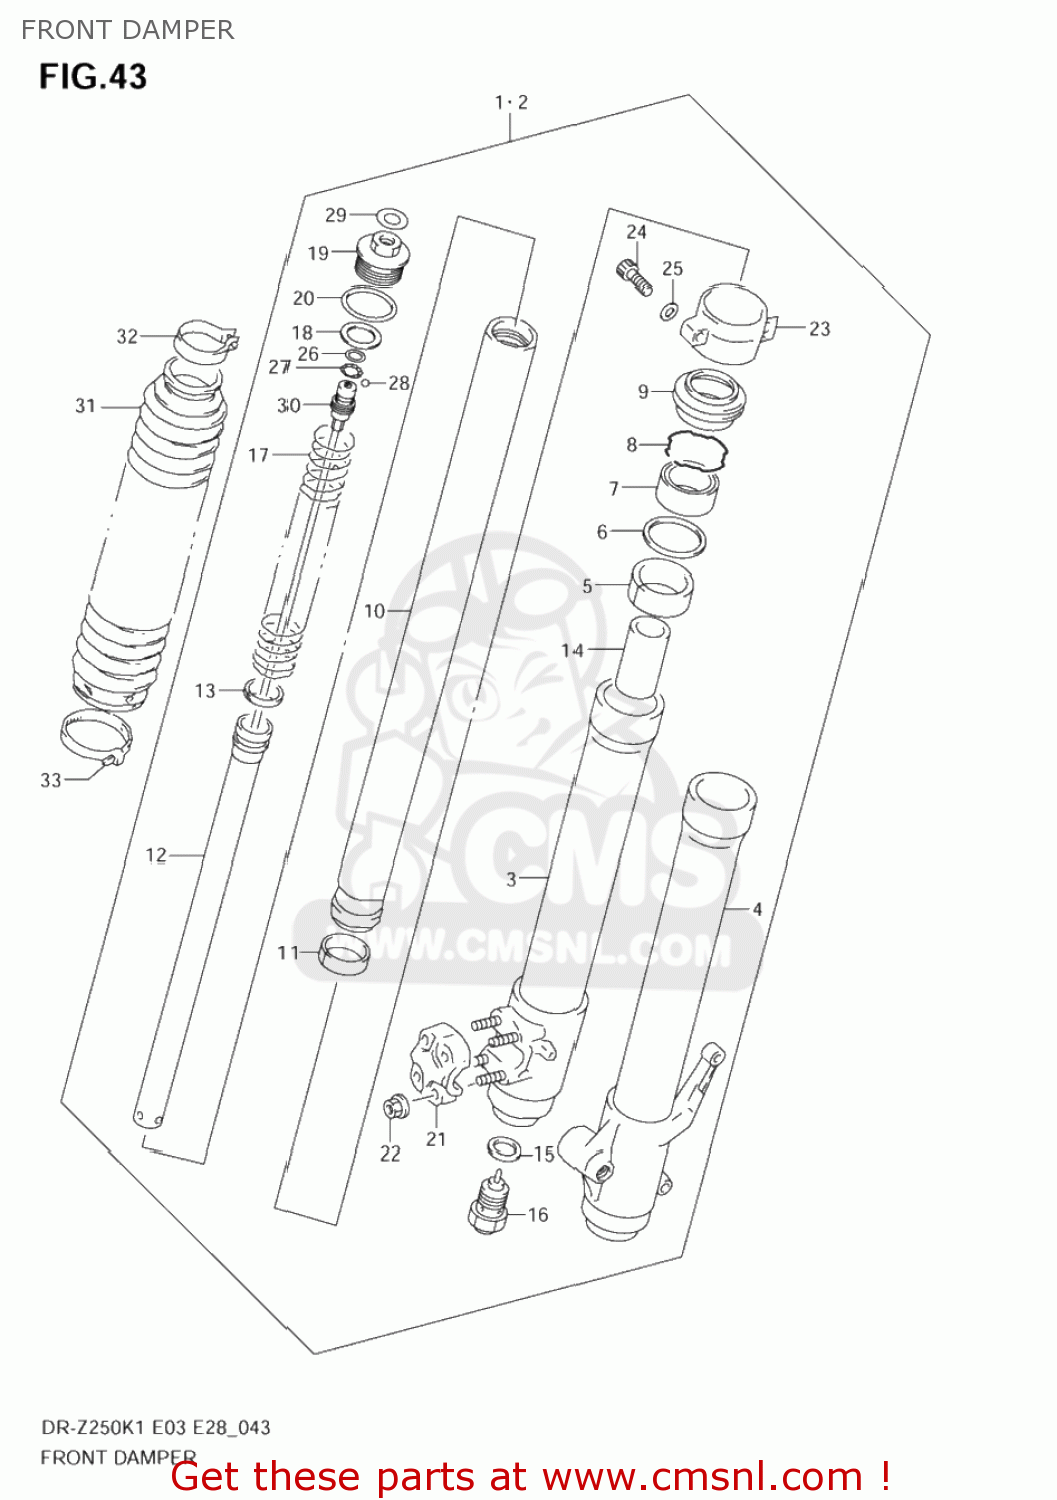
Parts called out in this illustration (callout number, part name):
1	DAMPER ASSY,FR FORK,R
2	DAMPER ASSY,FR FORK,L
3	TUBE,OUTER,R
4	TUBE,OUTER,L
5	BUSH,GUIDE
6	SPACER,SEAL
7	SEAL,OIL
8	CIRCLIP,FORK OIL SEAL
9	DUST SEAL
10	TUBE,INNER
11	BUSH,SLIDE
12	ROD,FR DAMPER
13	BUSH,SLIDE
14	PIECE,OIL LOCK
15	GASKET (NAS)
16	CTR BOLT
17	SPRING,FR
18	SEAT,SPRING LWR
19	BOLT,FORK
20	O RING
21	HOLDER,AXLE
22	NUT
23	HOLDER
24	BOLT
25	WASHER(5.5X10X1)
26	O RING(D:2.5,ID:13.8)
27	EXPANDER
28	BALL
29	LABEL (TEN S-H)
30	CASE,ADJUSTER
31	BOOT(BLACK)
32	BAND,BOOT UPR
33	BAND,BOOT LWR
